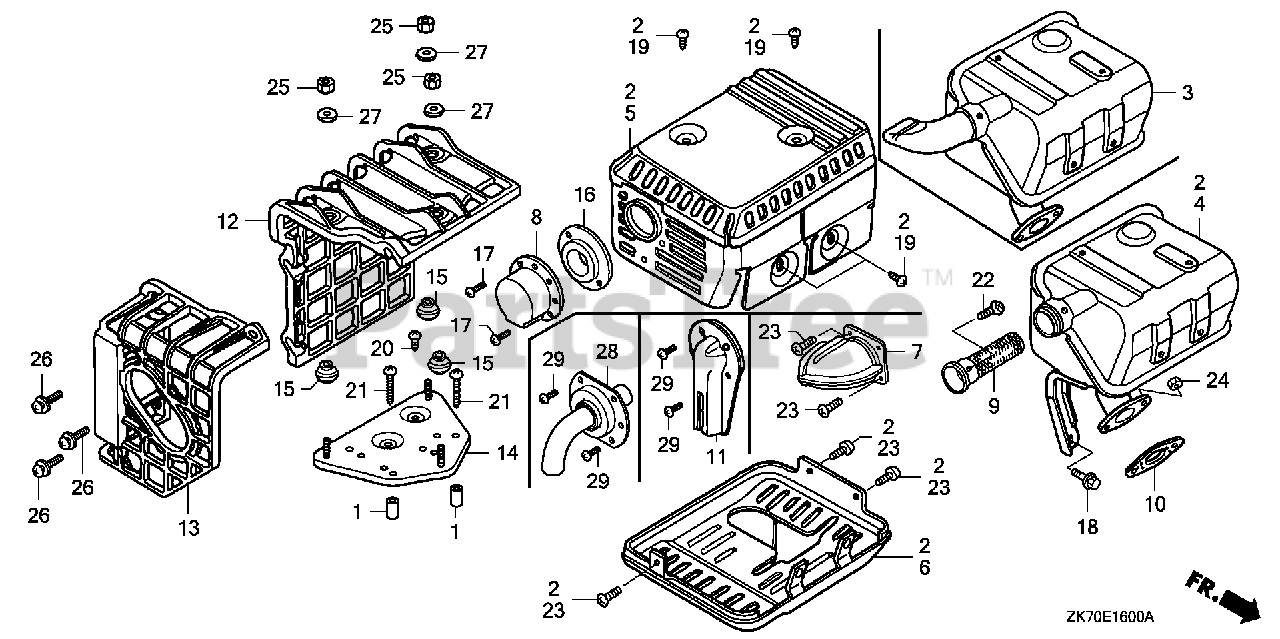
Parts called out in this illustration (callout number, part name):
4	MUFFLER (ARRESTER)
5	PROTECTOR, MUFFLER (STD) (BLACK)
9	ARRESTER, SPARK
10	GASKET, MUFFLER
19	SCREW, TAPPING (5X8)
22	SCREW, TAPPING (4X6)
24	NUT, HEX. (8MM)
